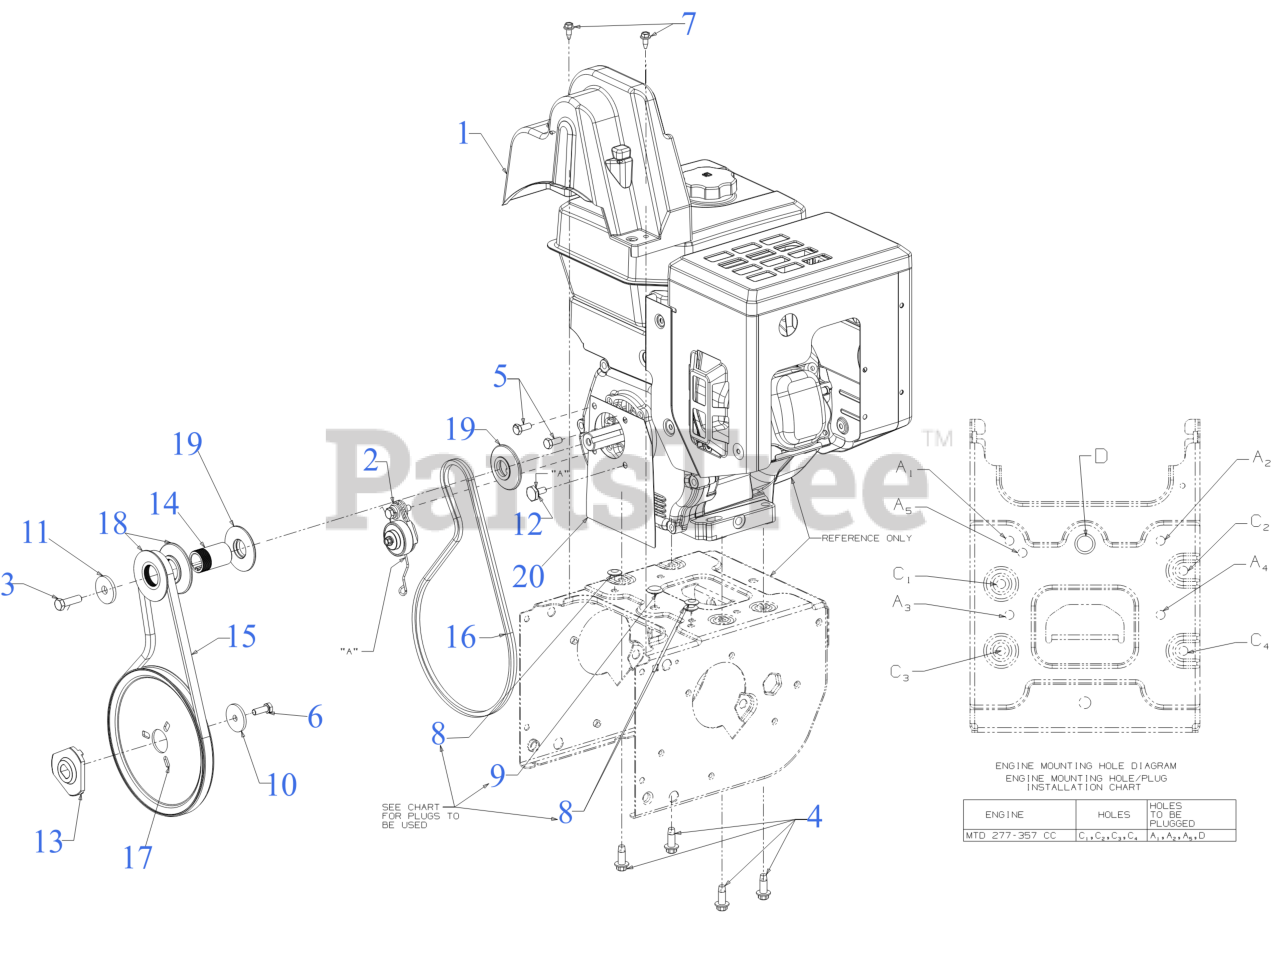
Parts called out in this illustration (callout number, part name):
1	BELT COVER SERVICE KIT (631-05323)
2	IDLER ASSEMBLY
3	SCREW 3/8-16 x 1
3	SCREW 3/8-24X1.25
4	SCREW 3/8-16 x 1
5	SCREW 5/16-24 x .750 GR5
6	SCREW 5/16-24 x .875 GR5
7	SCREW 1/4-20X.625
8	PLUG-3/8 DIA ID x 3/32
9	PLUG-1/2 ID x 3/32
10	FLAT WASHER
11	FLAT WASHER .45 x 1.5 x .172 HT
12	SHOULDER SCREW
13	ADAPTER PULLEY .75 DIA W/DD
14	PULLEY SPACER
15	BELT-.500 x 37.00
16	BELT-3L x 36.64 LG
17	AUGER PULLEY
18	HALF PULLEY 4L V x 2.6 OD
19	HALF PULLEY 3/8-V x 2.2
20	ENGINE PLATE (FRONT COVER)
